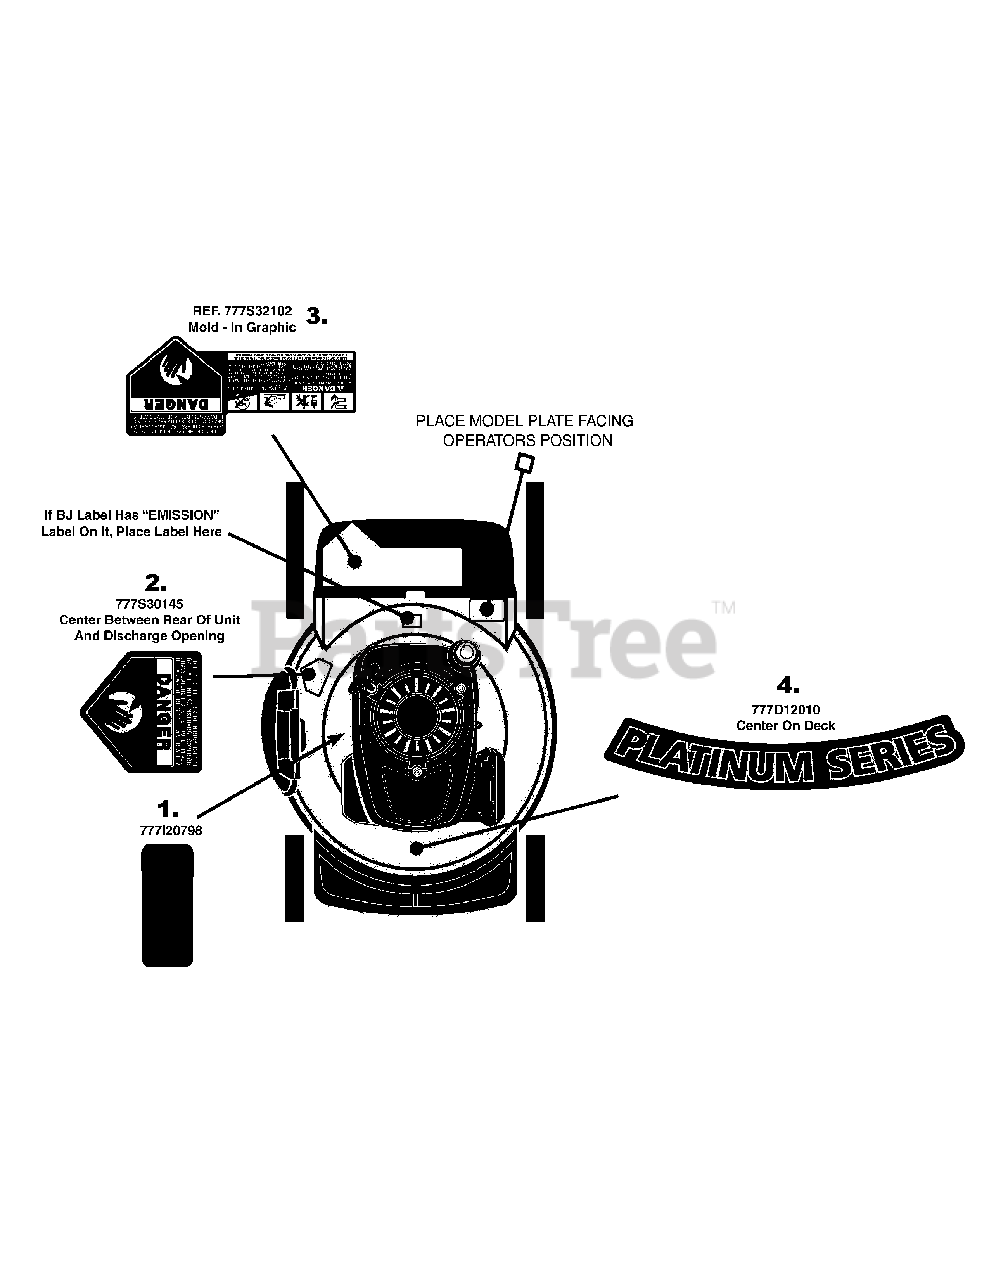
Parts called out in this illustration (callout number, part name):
1	LABEL-SHROUD
2	LABEL
3	LABEL
4	LABEL-MOWER DECK PLATINUM SERIES
